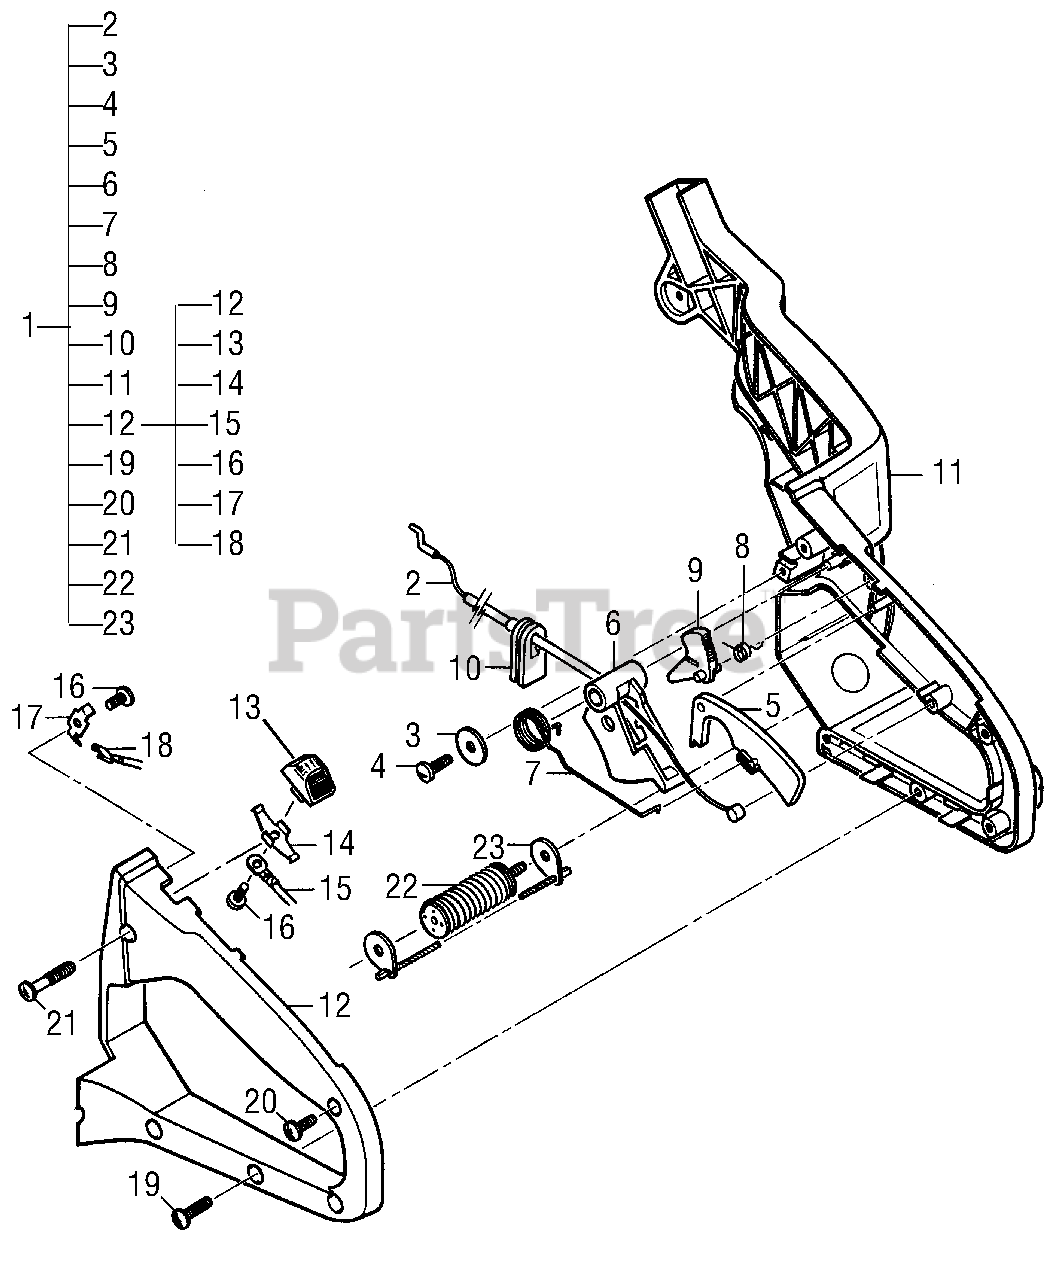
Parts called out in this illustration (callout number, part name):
1	Handle/Trigger Asy
2	Cable, Throttle
3	Washer, .19idx.68od
4	Screw, 8-16x.5 Torx
5	Release, Trigger
6	Trigger
7	Spring, Trigger
8	Spring, High Idle
9	Latch, High Idle
10	Grommet, Throttle
11	Frame, Rear
12	Cover Asy, Handle
13	Button, Stop Switch
14	Contact, Ignition Switch
15	Wire Asy
16	Screw, 8-16x.375 Plast
17	Contact, Ground
18	Wire, Ground Asy
19	Screw, Rear Frame Cover
20	Screw, 8-16x.5 Torx
21	Screw, 8-16x1 Torx Plast
22	Isolator Asy, Handle
23	Safety Cable Asy
